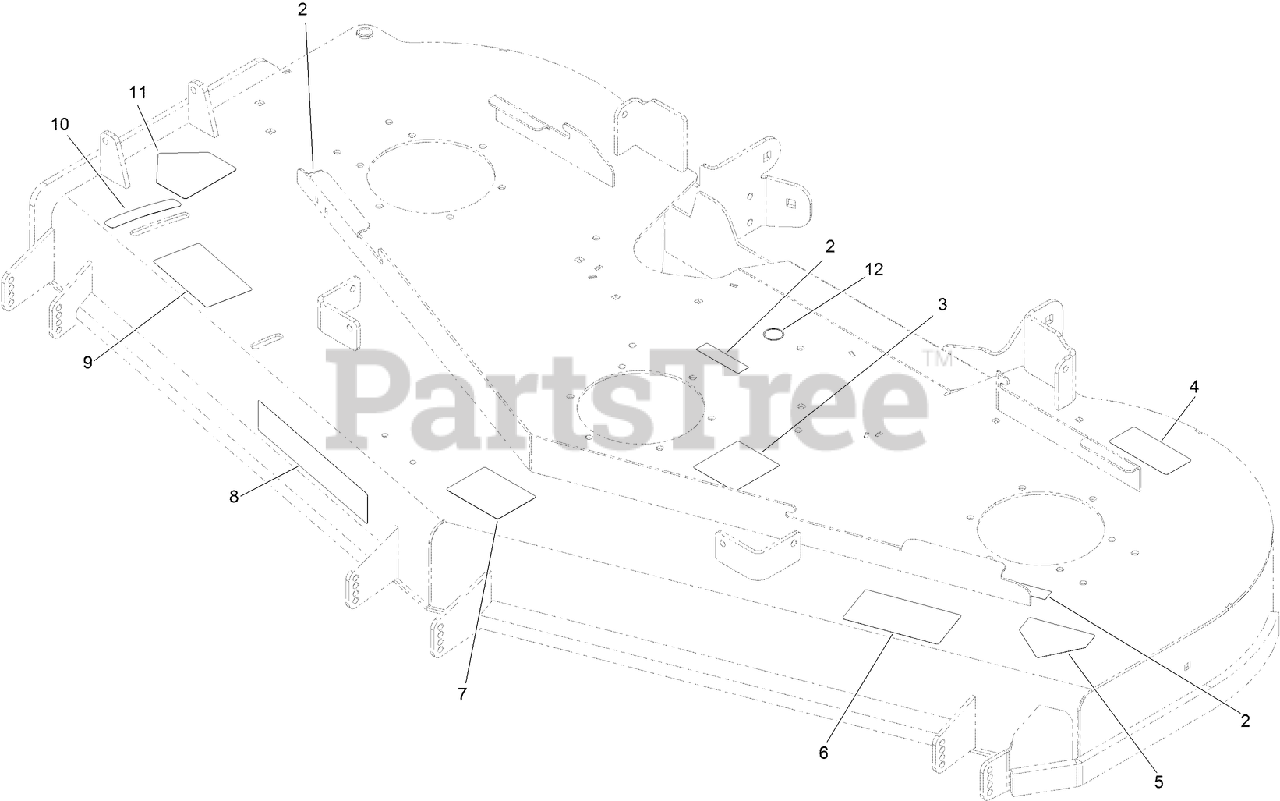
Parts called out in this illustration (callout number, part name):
2	DECAL-COVER, MISSING
3	DECAL-ROUTING, DECK BELT
4	DECAL-TORQUE
5	DECAL-DANGER
6	DECAL-DANGER, THROWN OBJECT
7	DECAL-SCALP, ANTI
9	DECAL-ADJUSTMENT, BAFFLE
10	DECAL-SETTING, BAFFLE
11	DECAL-DANGER
12	DECAL-GREASE
